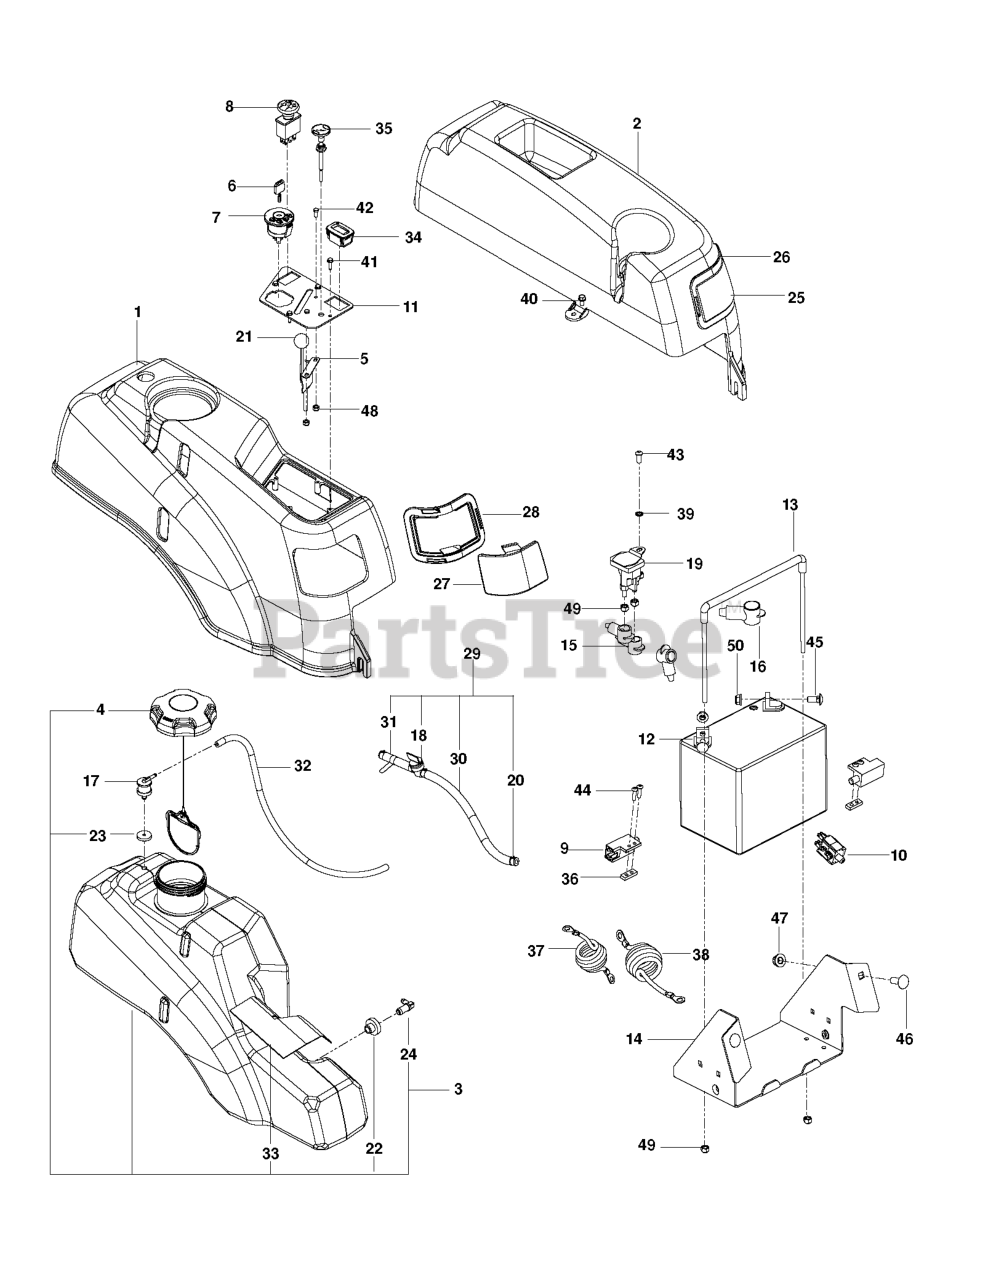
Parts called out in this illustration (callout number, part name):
1	FENDER RT, GRAY
2	FENDER, LT
3	TANK.FUEL.ASSEMBLY.LARGE
4	CAP, FUEL
5	THROTTLE CABLE
6	KEY MLD GEN DELTA
7	RP IGNITION SWITCH
8	SWITCH.INTRLCK.CLUTCH.
9	SWITCH INTERLOCKT
10	SWITCH, BRAKE 3P
11	CONTROL PLATE RZ STD X431
12	BATTERY, 12 V 330 AMP
13	BATTERY TIE DOWN ASSEMBLY
14	BOX BATTERY RZ BLACK
15	TERMINAL COVER
17	VALVE.FUEL.CHECK
18	FUEL VALVE
19	SOLENOID.W/BRASS.PLUNGER
20	HOSE CLAMP
21	KNOB.ROUND.BALL.BLACK
22	RUBBER GROMMET
23	GROMMET, CHECK VALVE
24	STEM, FUEL TANK
25	LENS, COLORED LEFT
26	LEFT HEADLIGHT RIM GREY
27	LENS, COLORED RIGHT
28	RT HEADLIGHT RIM GREY
29	FUEL LINE ASSY
30	GAS LINE 10"
31	FUEL LINE 3"
32	HOSE, FUEL, 3/16" X 17-1/4"
33	SHIELD, HEAT
34	GUAGE.SRVCMNDR.HRMTR.
35	CHOKE CABLE
36	PLATE NUT ZTR
37	BATTERY CABLE, NEGATIVE
38	CABLE POSITIVE, LONG
39	WASHER 1/4 INT TOOTH
40	SCREW
41	SCR #10-12X3/4 HEX WAS HD ZD
42	HCS #10-24 X 1/2
43	SCR 1/4-20 X 5/8 BTN SKT HD ZD
44	SCR #10-24 X .75 SKT HD BLK
45	RP BOLT 5/16-18 X3/4 ZN/YEL GR
46	BOLT D
47	NUT 3/8-16 HEX FLG NYLOC ZD
48	NUT 10-24 NYLOC
49	LOCKNUT.NYLOC.1/4-20
50	5/16-18 NYLOC FLANGE NUT
